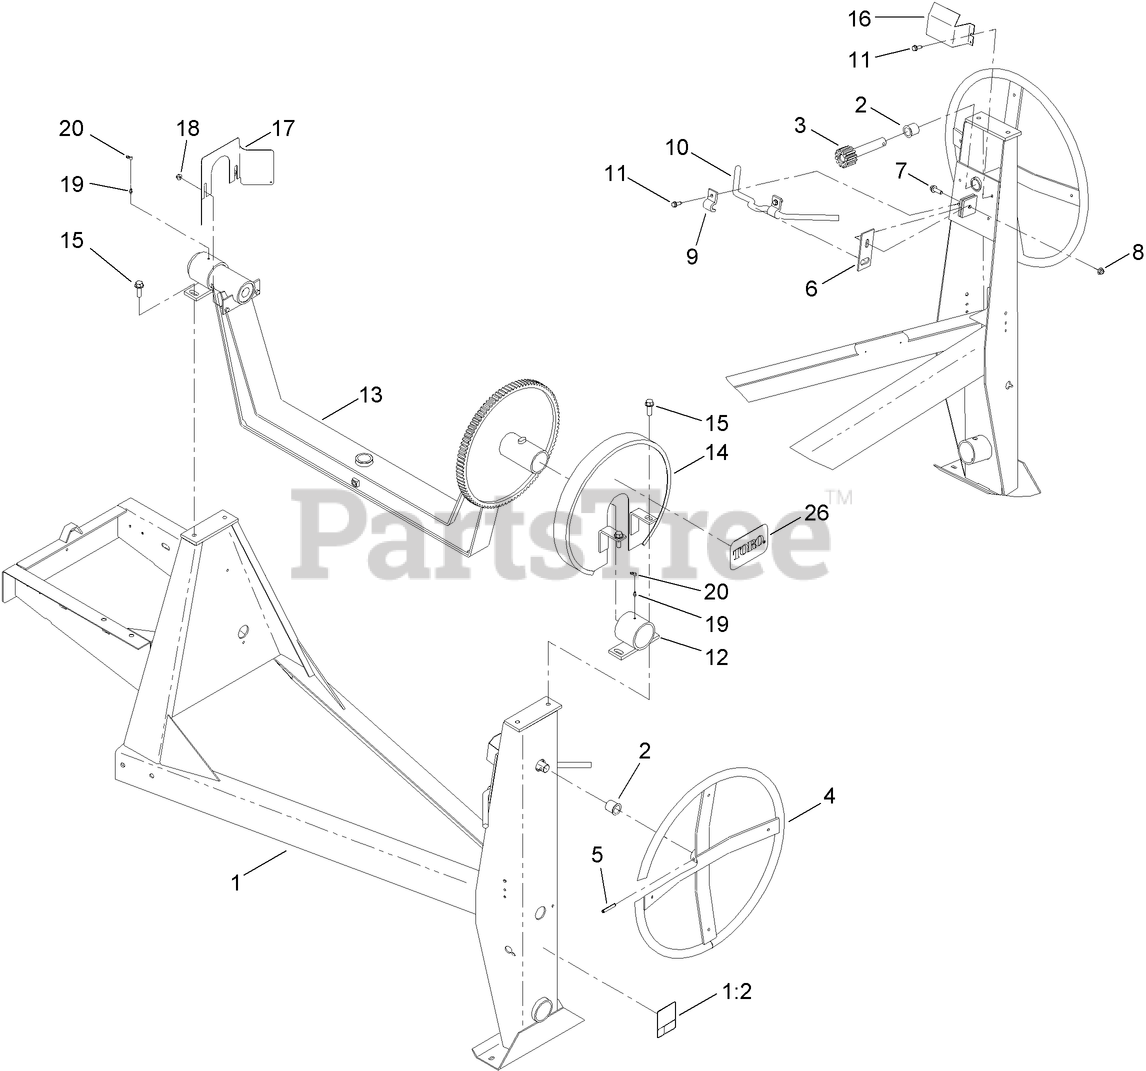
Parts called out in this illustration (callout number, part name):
1	FRAME ASM
1:2	DECAL-SAFETY CHAIN, TOWING
2	BUSHING-NYLON
3	SHAFT-TILT
4	HANDWHEEL
5	PIN-ROLL
6	DOG-BRAKE
7	SCREW-HHF
8	NUT-HF, NI
9	BRACKET-HANDLE
10	HANDLE-BRAKE
11	SCREW-HWHTF
12	TRUNNION
13	YOKE ASM
14	GUARD-BRAKE, UPPER
15	SCREW-HWH
16	GUARD-BRAKE, LOWER
17	GUARD-PINION
18	NUT-HF, NI
19	FITTING-GREASE
20	CAP-PLUG
26	DECAL
